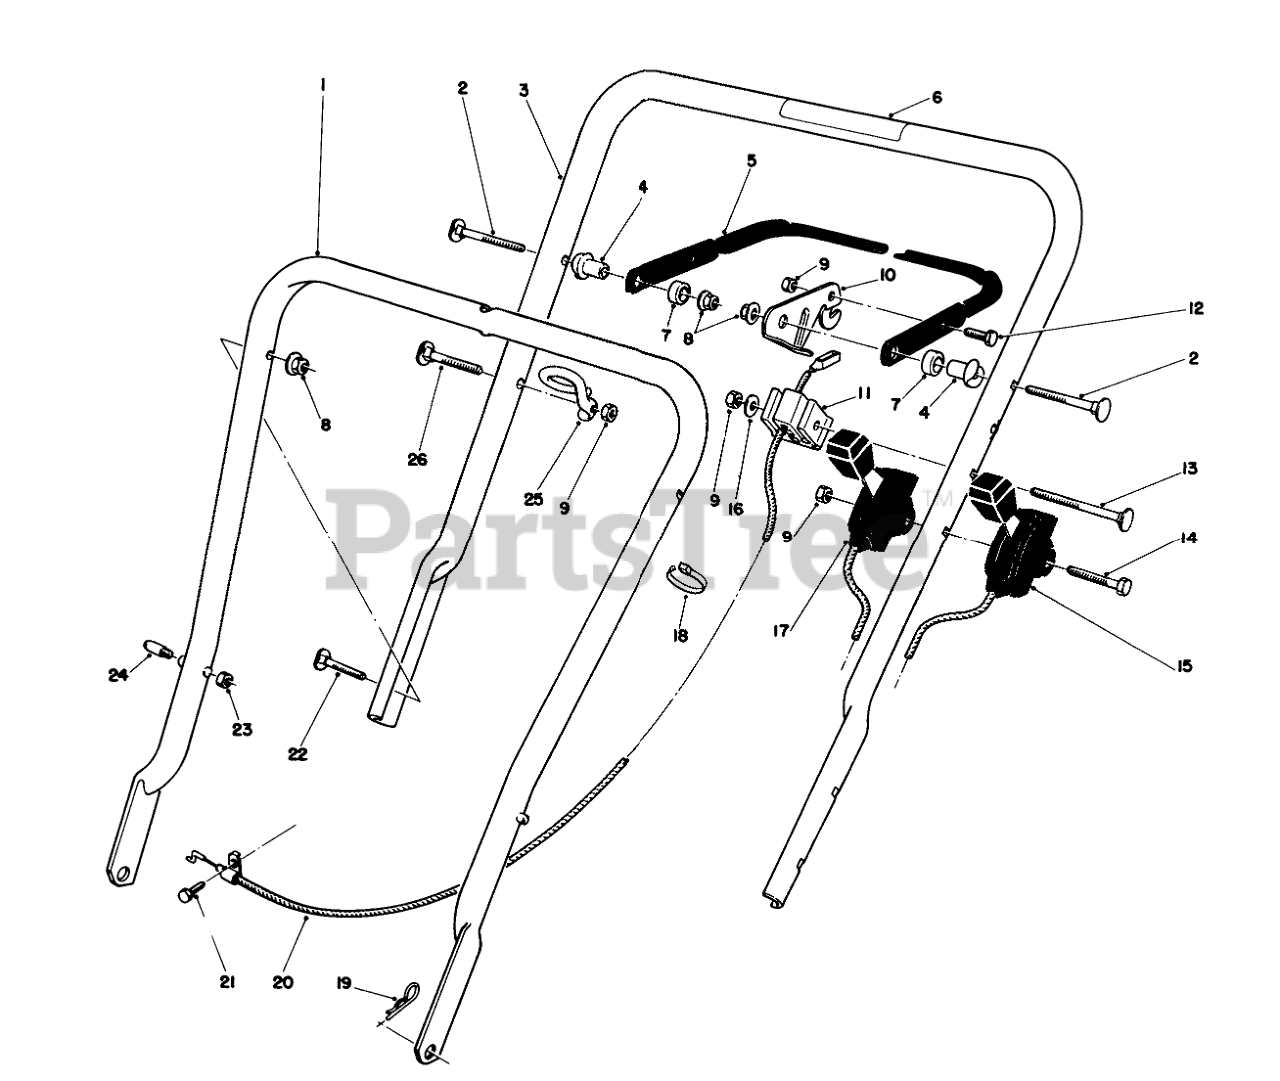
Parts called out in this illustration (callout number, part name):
1	LOWER HANDLE ASM
2	5/16-18 X 2 HNDLE SCREW
3	Handle-Upper (Incl. Ref. #6)
4	SPACER-SUPPORT
5	Bar-Control
6	Decal-Danger
7	SPACER-NYLON
8	NUT-LOCK, NI
9	NUT-LOCK, NI
10	CONTROL LEVER
11	SUPPORT-CABLE
12	SCREW-HH
13	HANDLE SCREW
14	SCREW-HH
15	TRACTION CONTROL
16	WASHER-FLAT
17	THROTTLE CONTROL - R&S
18	TIE-CABLE
19	PIN-COTTER, HAIR
20	BRAKE CABLE
21	SCREW-HH
22	SCREW
23	NUT-LOCK, NI
24	HANDLE PIN
25	Guide
26	HANDLE SCREW
